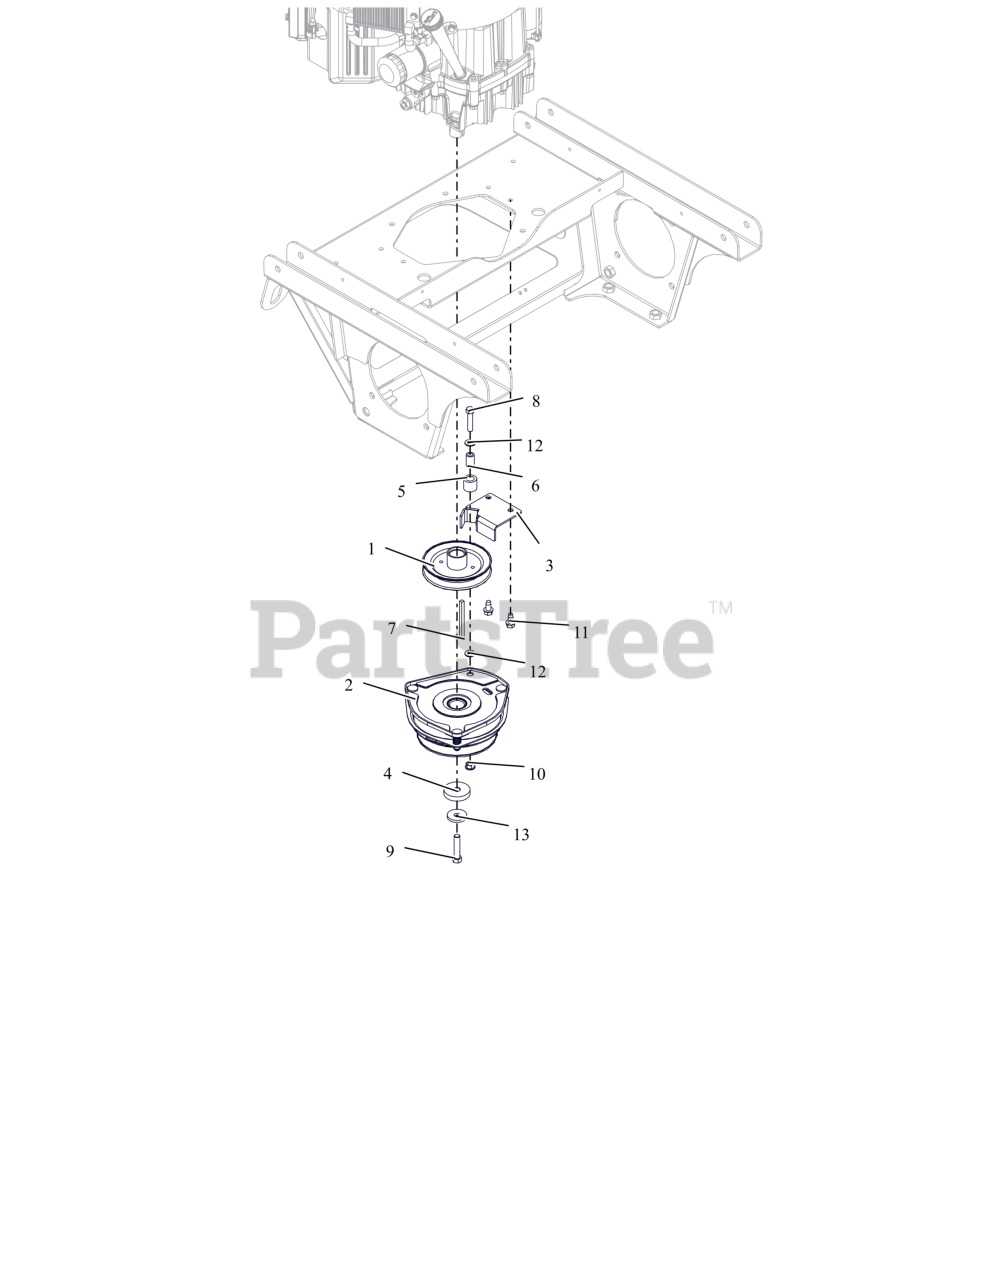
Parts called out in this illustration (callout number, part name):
1	SHEAVE-ENGINE 1.127ID X 5.25OD
2	CLUTCH, ELE-OGURA GT3.5-VP01R
3	CLUTCH STOP WLDMT - BLACK
4	SPACER, .450X2.00X.396
5	BUMPER,RUBBER .62X1.0X.88 LG
6	BUSH.,S.391X.622X.950 ST
7	KEY-SQ. .25X3.50X.25 SAE
8	BLT, HEX .38-16X1.75 G5 ZCC
9	BLT, HEX 0.4375-20X2 G8 ZCC NT
10	NUT-LK-TOP-FLG .38-16 ZC120
11	SCR,TAP .375-16X.75 HWH TR ZCC
12	WSHR,FLT .406X.812X.065 ZCC
13	WASHER, 7/16" SPRING DISK
